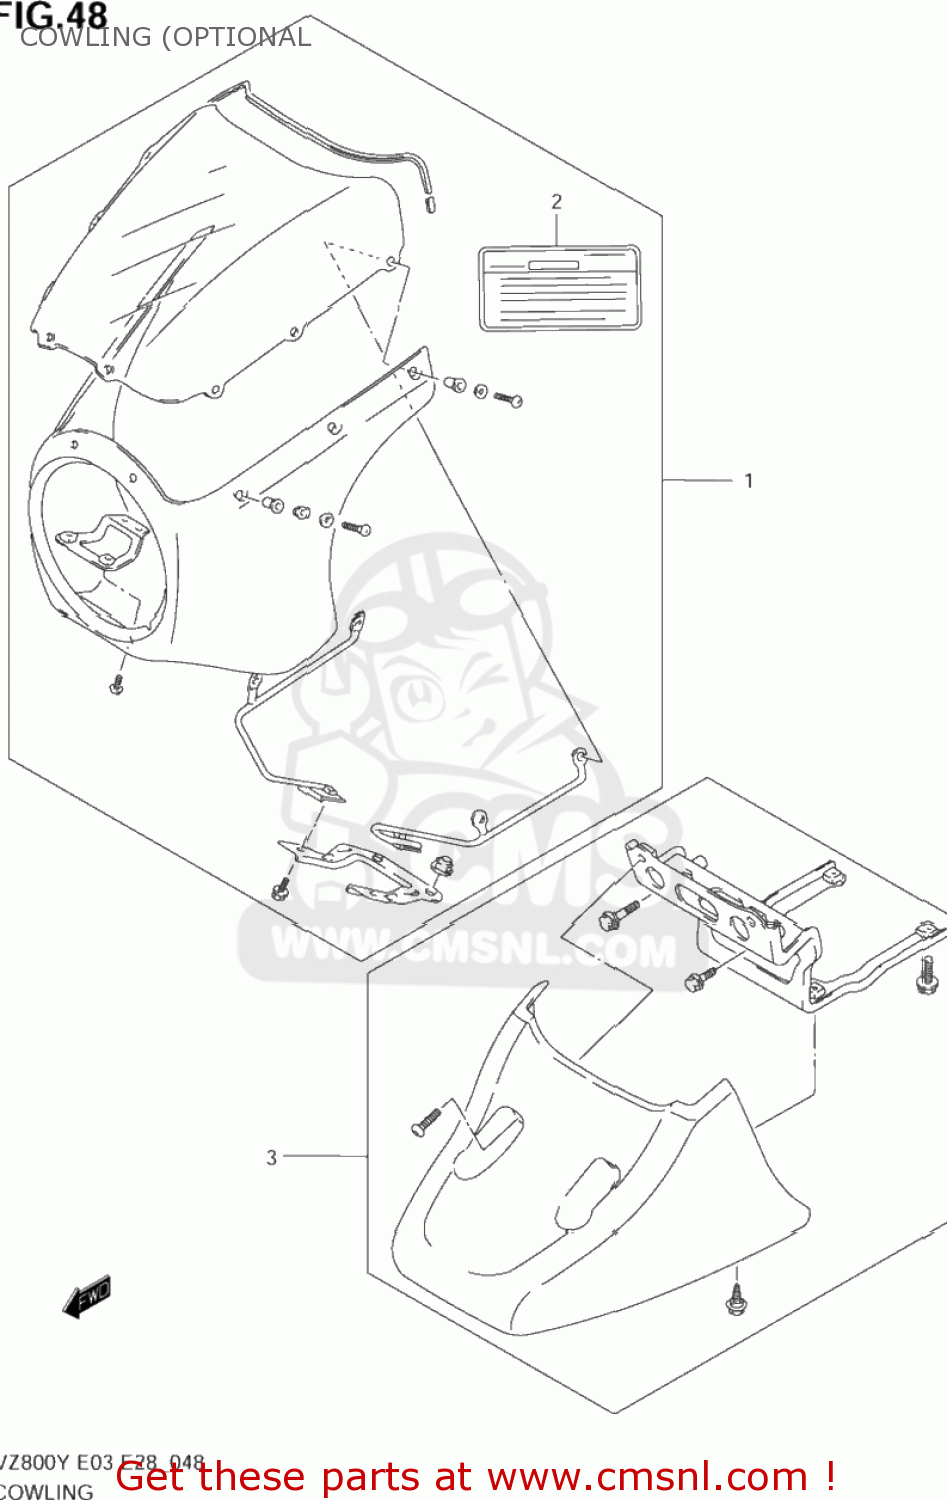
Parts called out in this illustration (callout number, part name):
1	COWLING ASSY,BODY
2	LABEL,WARNING SCREEN
3	COWLING,UNDER(BLUE)
